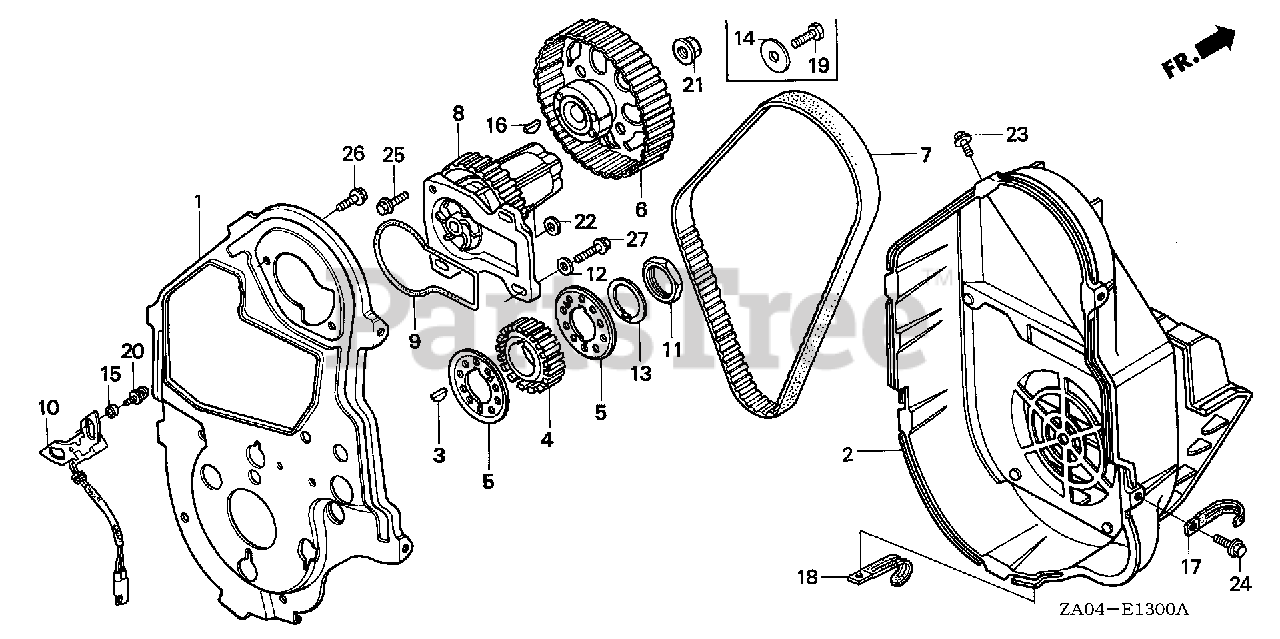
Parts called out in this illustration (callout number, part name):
1	COVER B, TIMING BELT
2	COVER, TIMING BELT
3	KEY, SPECIAL WOODRUFF (25X18)
4	PULLEY, TIMING
5	FLANGE, TIMING PULLEY
6	CAMSHAFT
6	PULLEY, CAMSHAFT
7	BELT, TIMING
8	WATER PUMP
9	O-RING, WATER PUMP
11	NUT, LOCK (30MM)
12	WASHER, PLAIN (6.5X15)
13	WASHER, LOCK (30MM)
14	WASHER, WHEEL (6MM)
14	WASHER, PLAIN (6MM)
16	KEY, CAM PULLEY
18	CLIP (6X20)
19	BOLT, HEX. (6X16)
21	NUT, FLANGE (10MM)
22	WASHER, PLAIN (6MM)
23	BOLT, FLANGE (6X10)
24	BOLT, FLANGE (6X12) Use from Engine SN 2086984.
25	BOLT, FLANGE (6X22)
26	BOLT, FLANGE (6X12)
27	BOLT, FLANGE (6X22)
